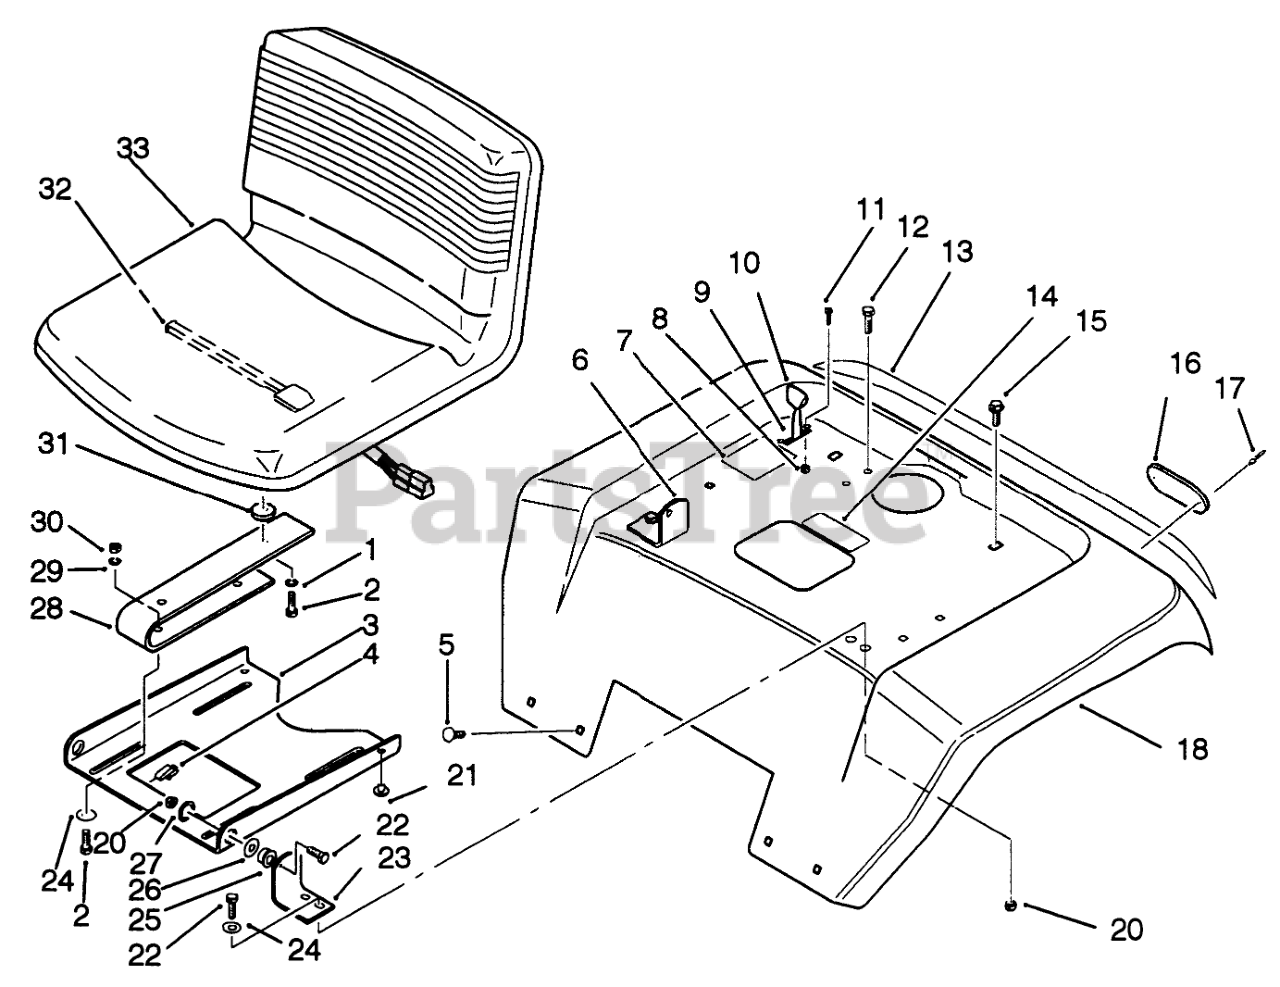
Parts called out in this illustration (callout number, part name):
1	WASHER-LOCK
2	SCREW-HH
3	Plate-SeatPivot
4	J-CLIP
5	SCREW-CARR
6	Bracket-Pivot RH
7	DECAL-PUSH
8	Nut
9	CONTROL-PUSH VALVE
10	KNOB-THROTTLE
11	SCREW
12	Screw-Hex Hd.
13	DECAL-FENDER
14	DECAL-DANGER
15	Screw
16	Reflector
17	Poprivet
18	WLDMT-FENDER R
20	NUT-LOCK, NI
21	BUMPER SJ5514 BLACK
22	SCREW-HH
23	BRKT-PIVOT L.H. B
24	WASHER-PLAIN
25	BUSHING
26	WASHER-SPECIAL
27	WASHER-SPRING
28	Seat Spring
29	WASHER-LOCK
30	NUT-HEX
31	SPACER-NYLON
32	SWITCH-SEAT
33	SEAT V-410
